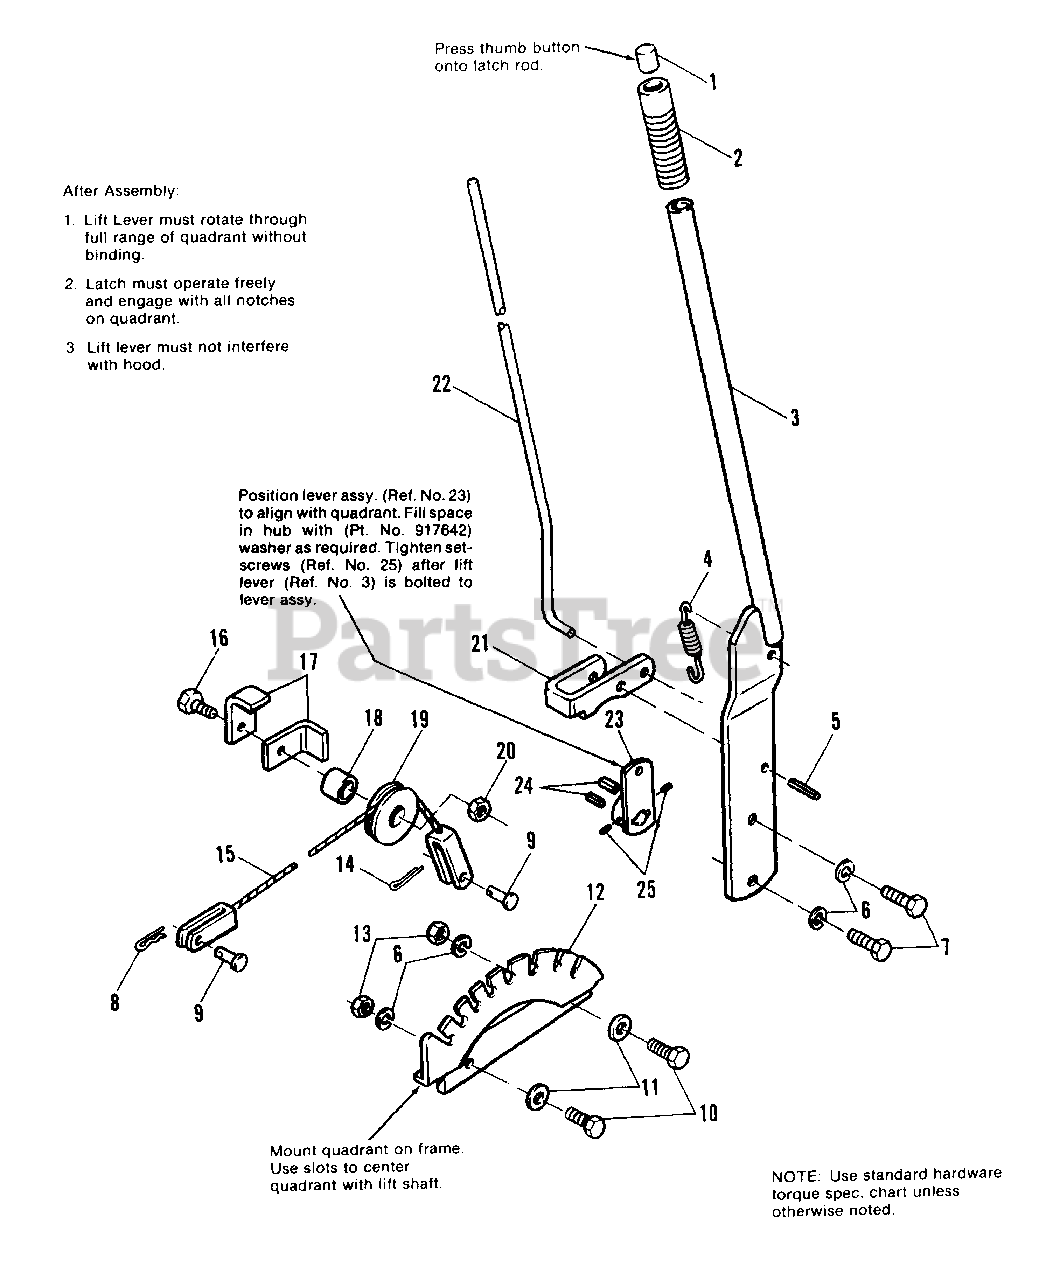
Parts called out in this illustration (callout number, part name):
2	GRIP
3	LEVER ASSY., Lift
5	PlN, Spring, 3/8 x 1-1/4
6	LOCKWASHER, 3/8
7	CAPSCREW, Hex Hd., 3/8-16 x 1
8	CLIP, Spring
10	CAPSCREW, Hex Hd., 3/8-16 x 7/8
11	WASHER, Plain, 5/16
13	NUT, Hex, Full, 3/8-16
14	PIN, Cotter, 3/32 x 1
15	CABLE ASSY., Lift
16	SCREW, Special
17	GUARD, Cable
20	LOCKNUT, Hex, Jam, 3/8-16
21	LATCH, Lift Lever
22	ROD, Latch
23	LEVER ASSY., Lift
25	SETSCREW, 5/16-18 x 1/4
